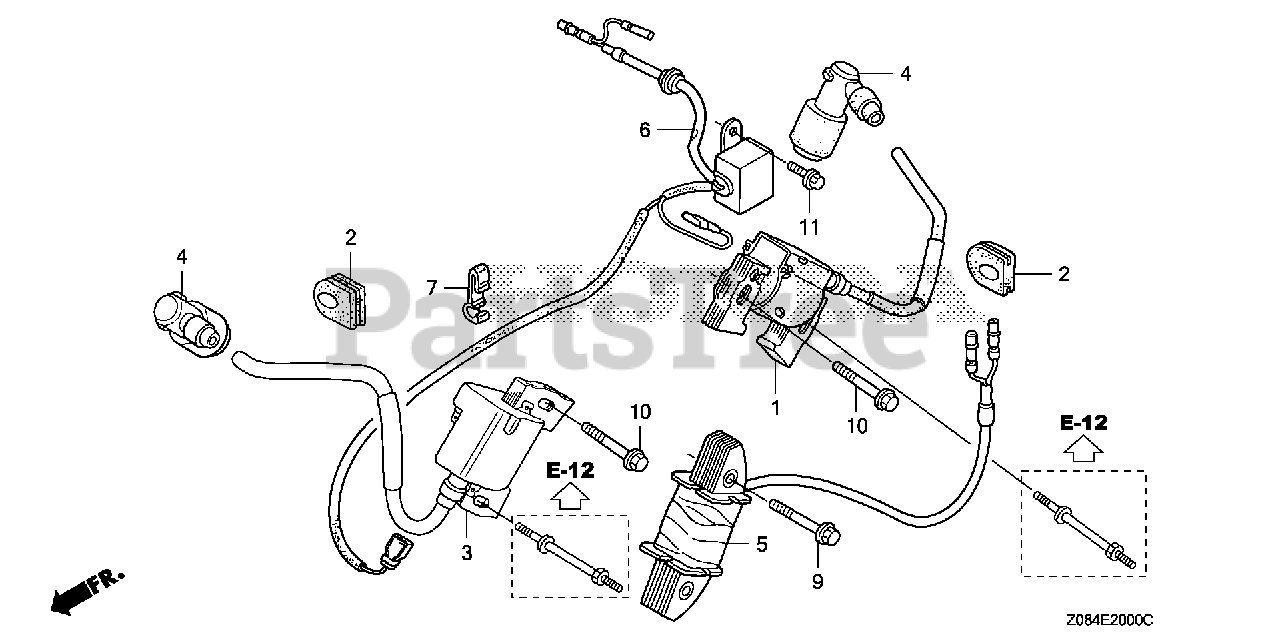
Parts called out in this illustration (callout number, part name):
1	COIL ASSY., IGNITION (200MM) (BLACK)
2	GROMMET, IGNITION WIRE
3	COIL ASSY., IGNITION (215MM) (GRAY)
4	CAP ASSY., NOISE SUPPRESSOR
5	COIL ASSY., CHARGE (12V/3A)
6	DIODE ASSY., ENGINE STOP
7	CLAMP, WIRE
9	BOLT, FLANGE (6X35) (CT200)
10	BOLT, FLANGE (6X32) (CT200)
11	BOLT, FLANGE (6X8)
